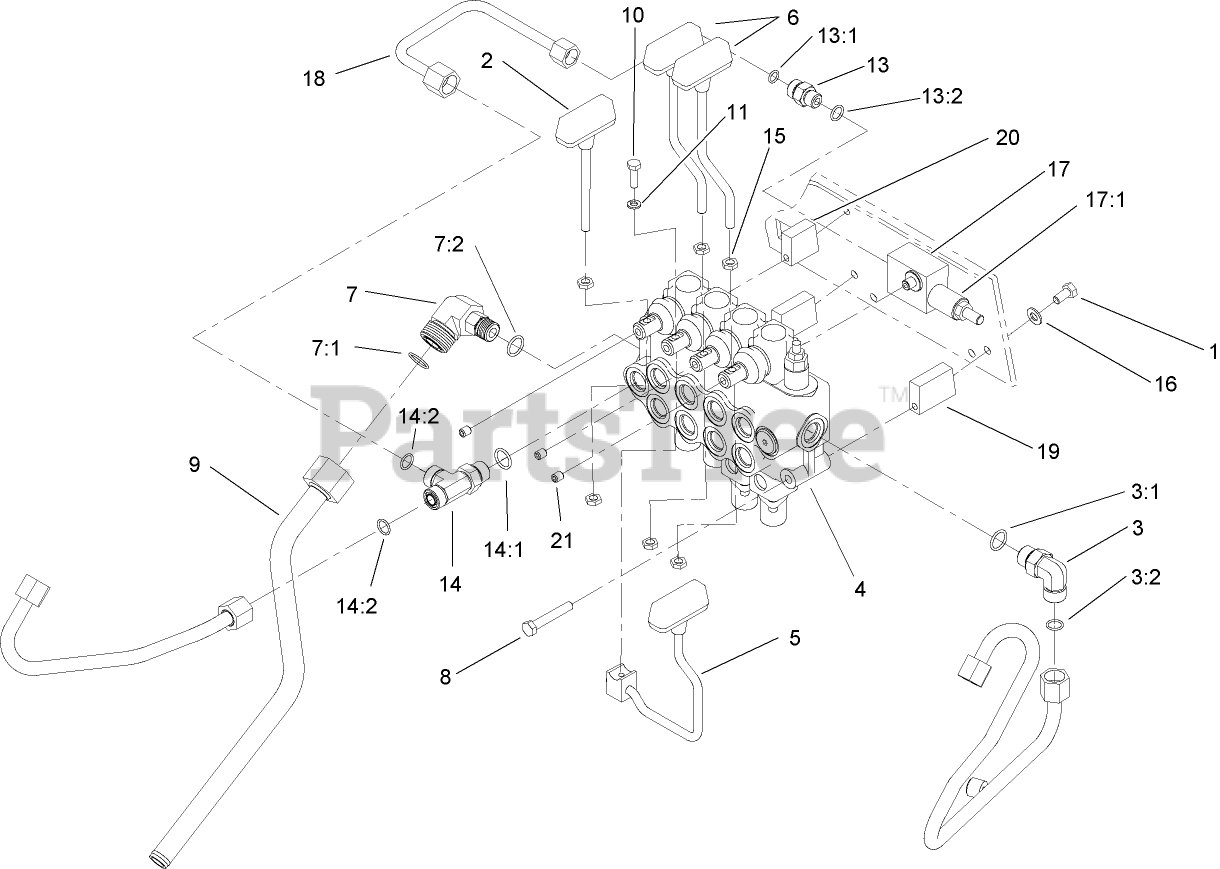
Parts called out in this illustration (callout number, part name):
1	SCREW-HH
2	LEVER-CYLINDER
3	FITTING-ELBOW-90 DEG
3:1	O-RING
3:2	O-RING
4	HYD FOUR SPOOL VALVE ASM
5	LEVER-CONTROL
6	LEVER-DRIVE
7	FITTING-HYD, 90 DEG
7:1	O-RING
7:2	O-RING
8	SCREW-HH
9	TUBE-TANK, HYD
10	SCREW-HH
11	WASHER-LOCK
13	FITTING-STRAIGHT
13:1	O-RING
13:2	O-RING
14	FITTING-TEE
14:1	O-RING
14:2	O-RING
15	NUT-HEX
16	WASHER-PLAIN
17	RELIEF VALVE ASM
17:1	CARTRIDGE-VALVE, RELIEF
18	LINE-HYD
19	SPACER-LOWER
20	SPACER-UPPER
21	SCREW-SET, HSH
